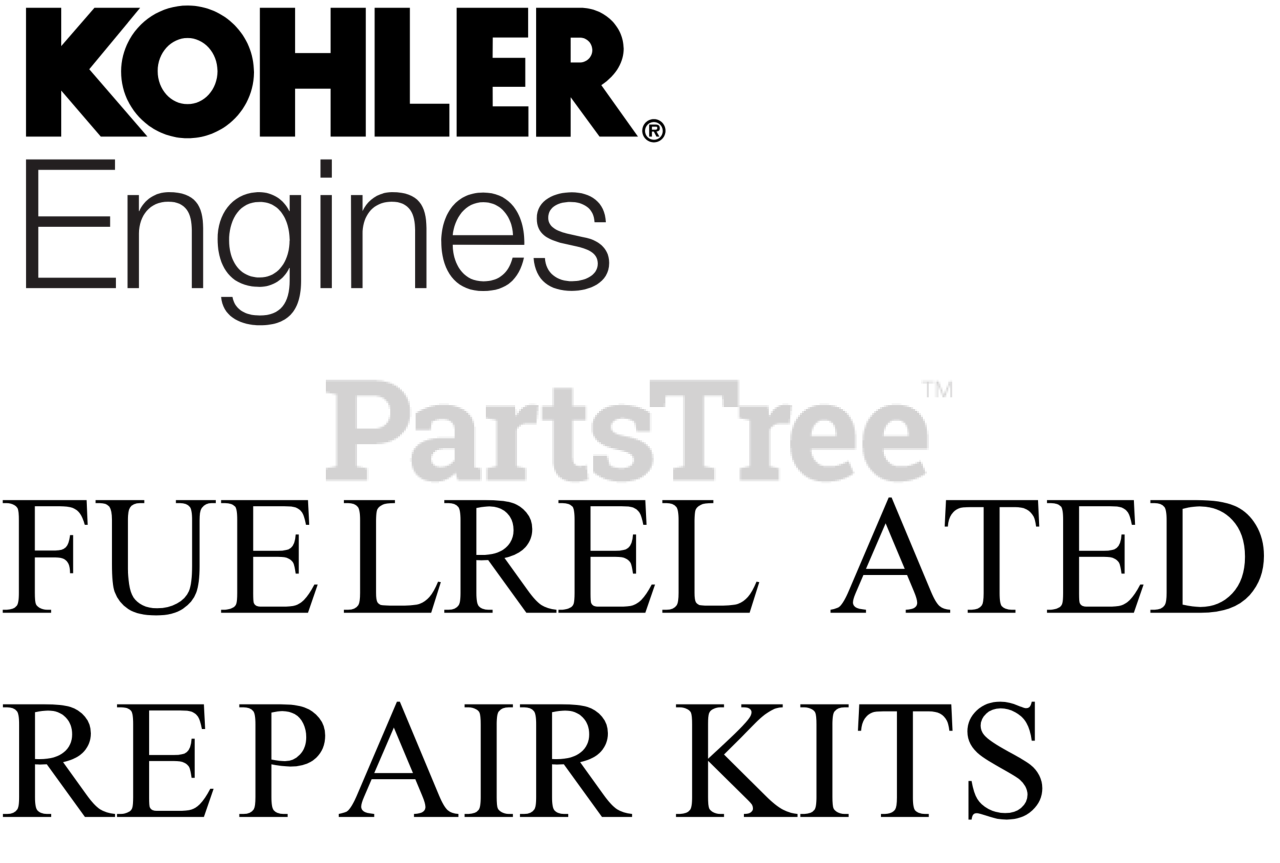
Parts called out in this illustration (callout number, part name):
NI	KIT, HIGH ALT4000 TO 8000 FT
NI	KIT, HIGH ALTITUDE (+ 8000 FT)
NI	KIT, FUEL SHUTDOWN-USE 24 757 76-S
NI	KIT, CHOKE REPAIR-USE 24 757 77-S
NI	KIT, ACCEL PUMP REPAIR
NI	KIT, CARBURETOR REPAIR
NI	KIT, FLOAT BOWL REPLACEMENT
